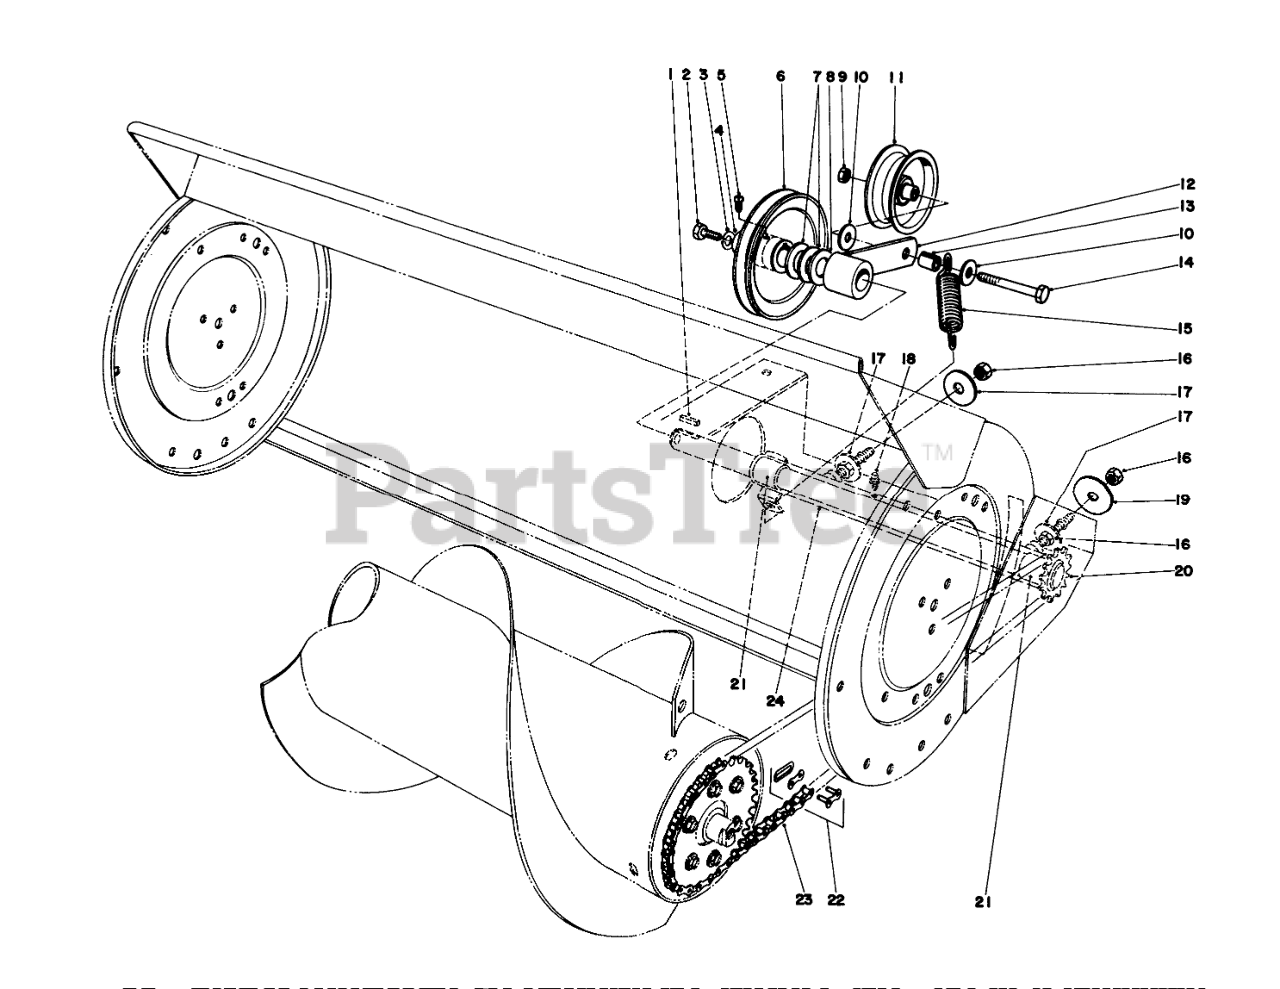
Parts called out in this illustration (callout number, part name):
1	KEY-SQUARE
2	SCREW-HH
3	WASHER-LOCK
4	WASHER-FLAT
5	SCREW-SQH
6	Pulley
7	Washer
8	Washer
9	NUT-LOCK, CONE
10	WASHER-FLAT
11	IDLER PULLEY ASM
12	Idler Arm
13	Spacer
14	SCREW-HH
15	Spring
16	NUT-HH
17	WASHER-FLAT
18	FITTING-GREASE
19	Flat Washer
20	SHAFT/SPROCKET ASM
21	Bushing-Jackshaft
22	LINK-CONNECTING
23	Roller Chain
24	Jackshaft Housing (Incl. Ref. #18)
